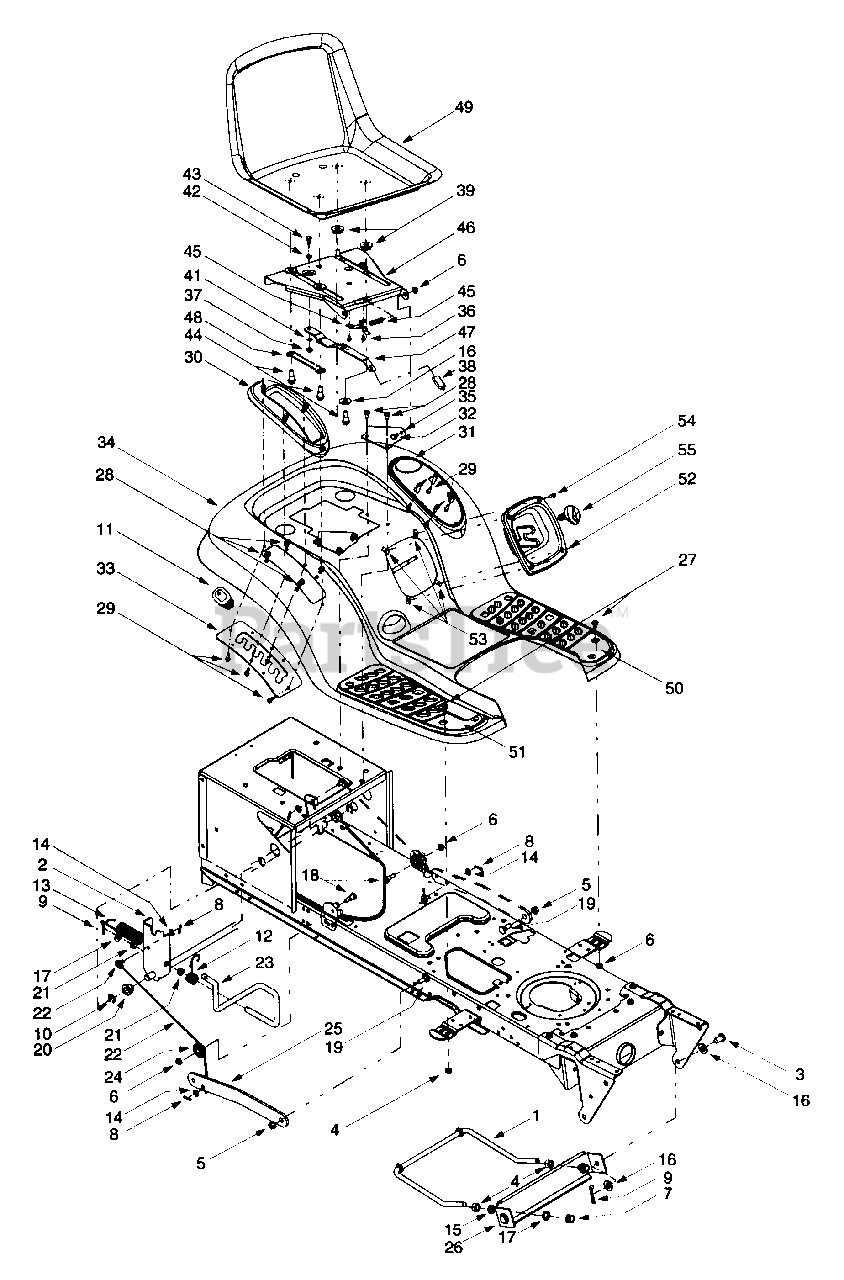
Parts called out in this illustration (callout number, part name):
3	Clevis Pin, .5 x .78
4	Hex Nut, 1/2-13
5	Flange Lock Nut, 3/8-16
6	Flange Lock Nut, 5/16-18
7	Hex Nut, 1/2-13
8	Internal Cotter Pin
9	Cotter Pin
11	Handle Grip
12	Torsion Spring
13	Lift-assist Spring, 1.15 x 5.99
14	Flat Washer, 5/16
15	Lock Washer, 1/2
16	Flat Washer, .31 x 1.062 x .134
17	Flat Washer, .51 x 1.12 x .06
18	Hex Cap Screw, 5/16-18 x .62
19	Shoulder Screw, .5 x .27, 3/8-16
20	Hex Flange Bearing
21	Snap Flange Bearing
22	Lift Cable, 16.16
23	Lift Handle
24	Roller Pulley
27	Carriage Bolt, 5/16 x.62
28	Self Tapping Screw, 5/16-18 x .625
29	Self Tapping Screw, 1/4-15 x .75
30	Lift Lever Cover
31	Cover w/ Cup Holder
32	Shoulder Screw, .437 x 1.62
36	Screw, #10-16 x .375
37	Hex Flange Lock Nut, 1/4-20
38	Seat Adjuster Grip
41	Spring Washer, .265 x .562 x .025
42	Flat Washer, .344 x .62 x .03
43	Shoulder Screw, .340 x .285, 1/4-20
44	Shoulder Screw, .50 x .50, 3/8-16
45	Seat Stop
48	Seat Adjustment Selector
49	Seat
50	LH Foot Pad
51	RH Foot Pad
52	Shift Cover
53	Speed Nut, 1/4-20
54	Phillips Screw, 1/4-20 x .75
55	Shift Knob
